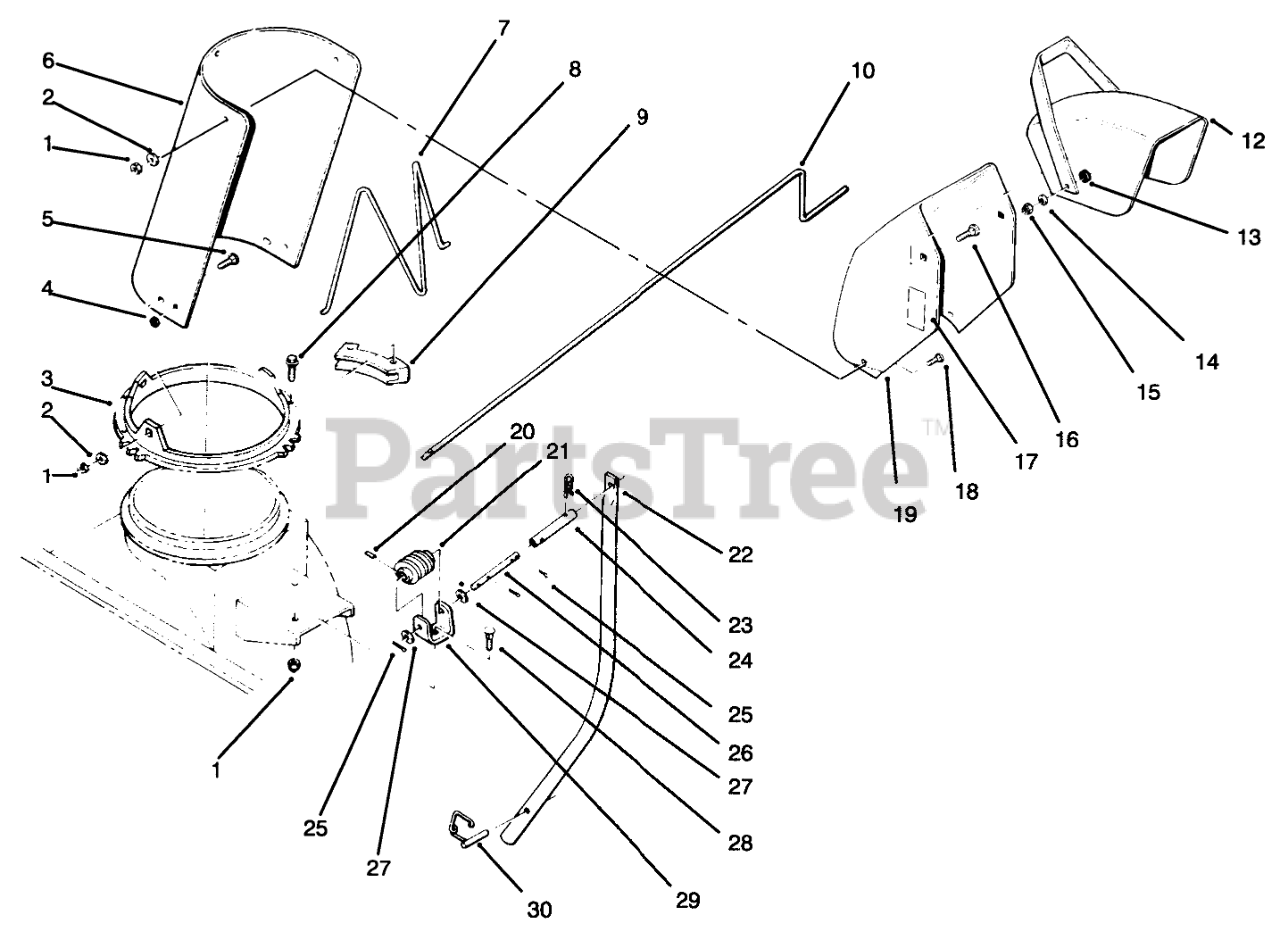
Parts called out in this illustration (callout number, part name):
1	NUT-LOCK, NI
2	WASHER-PLAIN
3	Screw
4	NUT-PUSH
5	SCREW-CARR
6	EXTENDER-CHUTE, UPPER
7	WIRE-CHUTE
8	SCREW-SPECIAL
9	RETAINER-CHUTE
10	ROD-CHUTE CONTROL
12	Deflector
13	WASHER-RUBBER
14	WASHER-BELLEVILLE
15	NUT-LOCK, NI
16	BOLT-CARR
17	DECAL-DANGER (only on: 38078)
18	SCREW-HH
19	Chute-Upper Discharge (Incl. Ref. #17)
20	PIN-SPRING
21	GEAR-WORM, CHUTE
22	TUBE-CRANK SUPPOR R
23	PIN-HAIR
24	COUPLING
25	PIN-COTTER
26	ROD-LOWER CHUTE CONT
27	WASHER-FLAT
28	BOLT-CARR
29	WORM BRKT B
30	LOCKING PIN ASM
